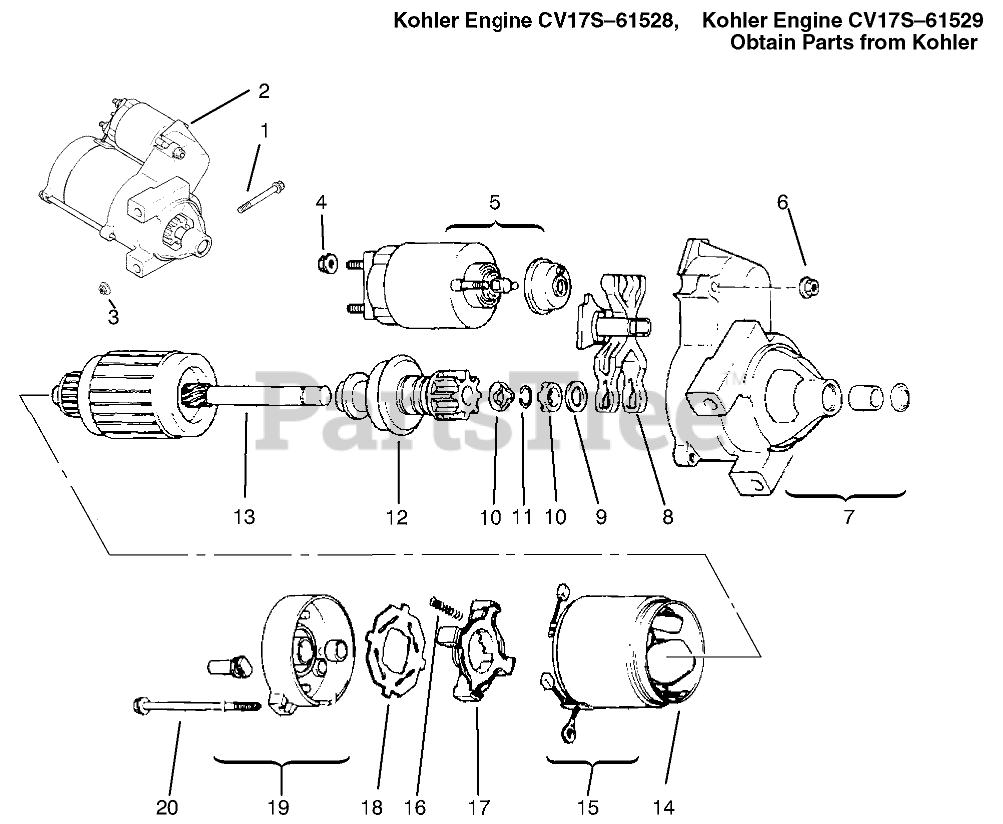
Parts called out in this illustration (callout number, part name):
2	Starter INC 4-20
4	Nut
5	Solenoid
6	Nut
7	Cap Drive End
8	Lever Starter Drive
9	Washer-Thrust
10	Nut
11	Ring-Retainer
12	Drive Pinion
13	Armature
14	Frame
15	Brush Kit
16	Spring Brush
17	Holder-Brush
18	Insulator
19	Cap-Commutator End
20	Bolt
